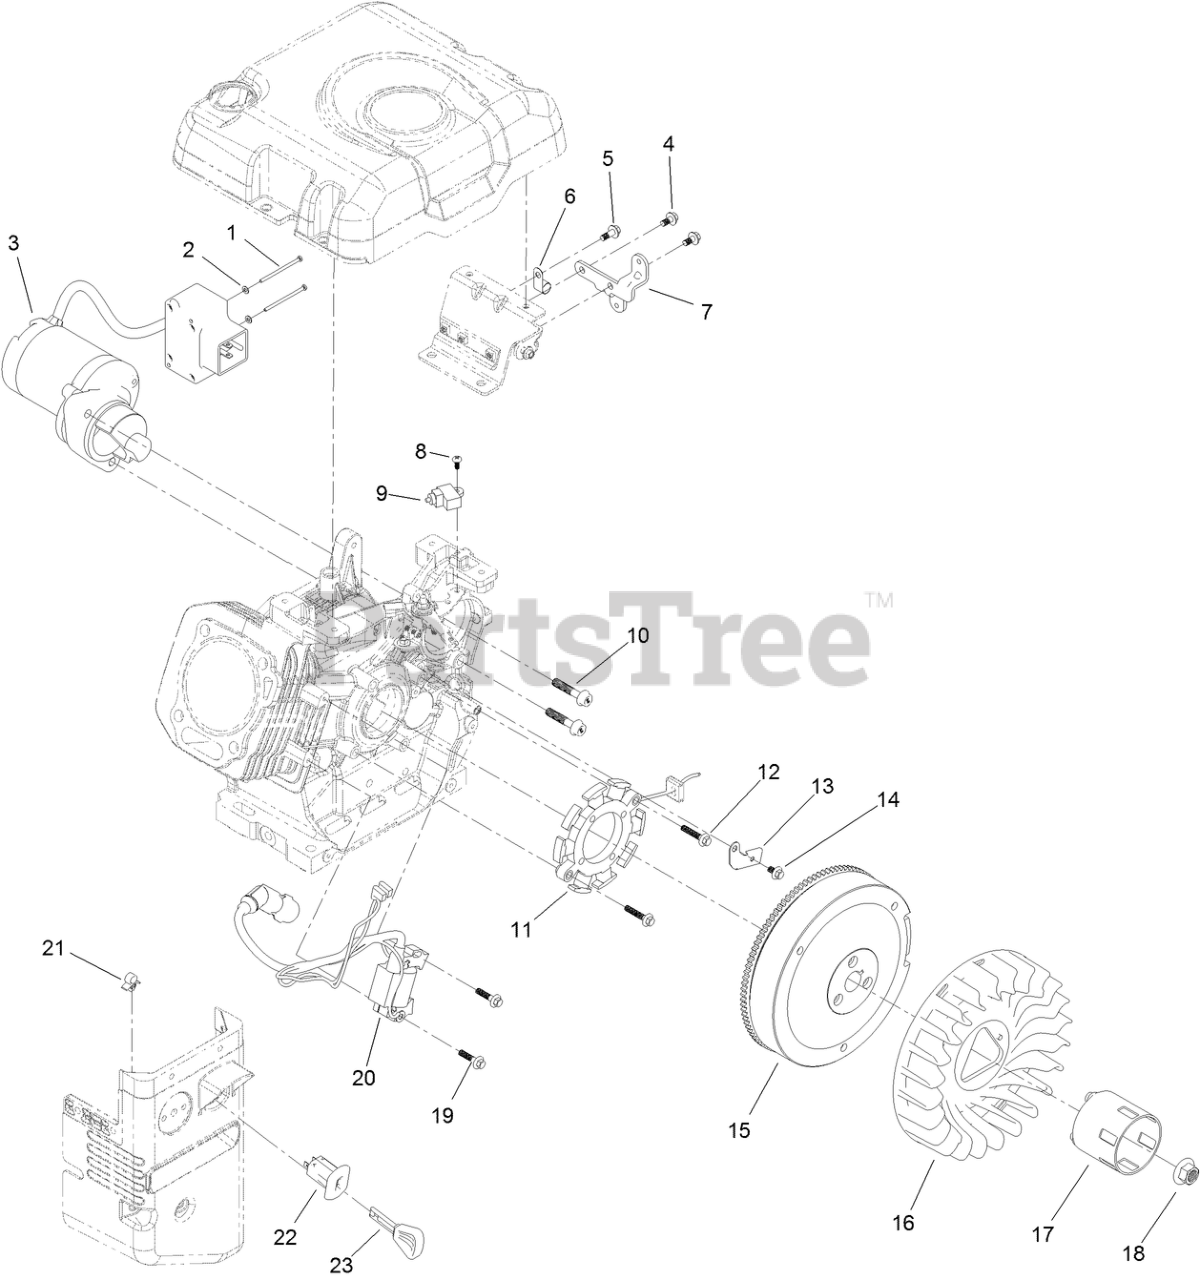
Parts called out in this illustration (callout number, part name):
1	SCREW-BHP
2	WASHER-PLAIN
3	MOTOR-STARTER
4	SCREW-HHF
5	SCREW-HHF
6	CLIP-HARNESS, WIRE
7	BRACKET-BOX, SWITCH
8	SCREW-PPH
9	SWITCH-STOP, ENGINE
10	SCREW-HHF
11	STATOR COIL ASM
12	SCREW-HHF
13	CLAMP-WIRE, CHARGE
14	SCREW-HHF
15	FLYWHEEL ASM
16	FAN-COOLING
17	CUP-STARTER
18	NUT-FLANGE
19	SCREW-HHF
20	IGNITION COIL ASM
22	SWITCH-KEY
